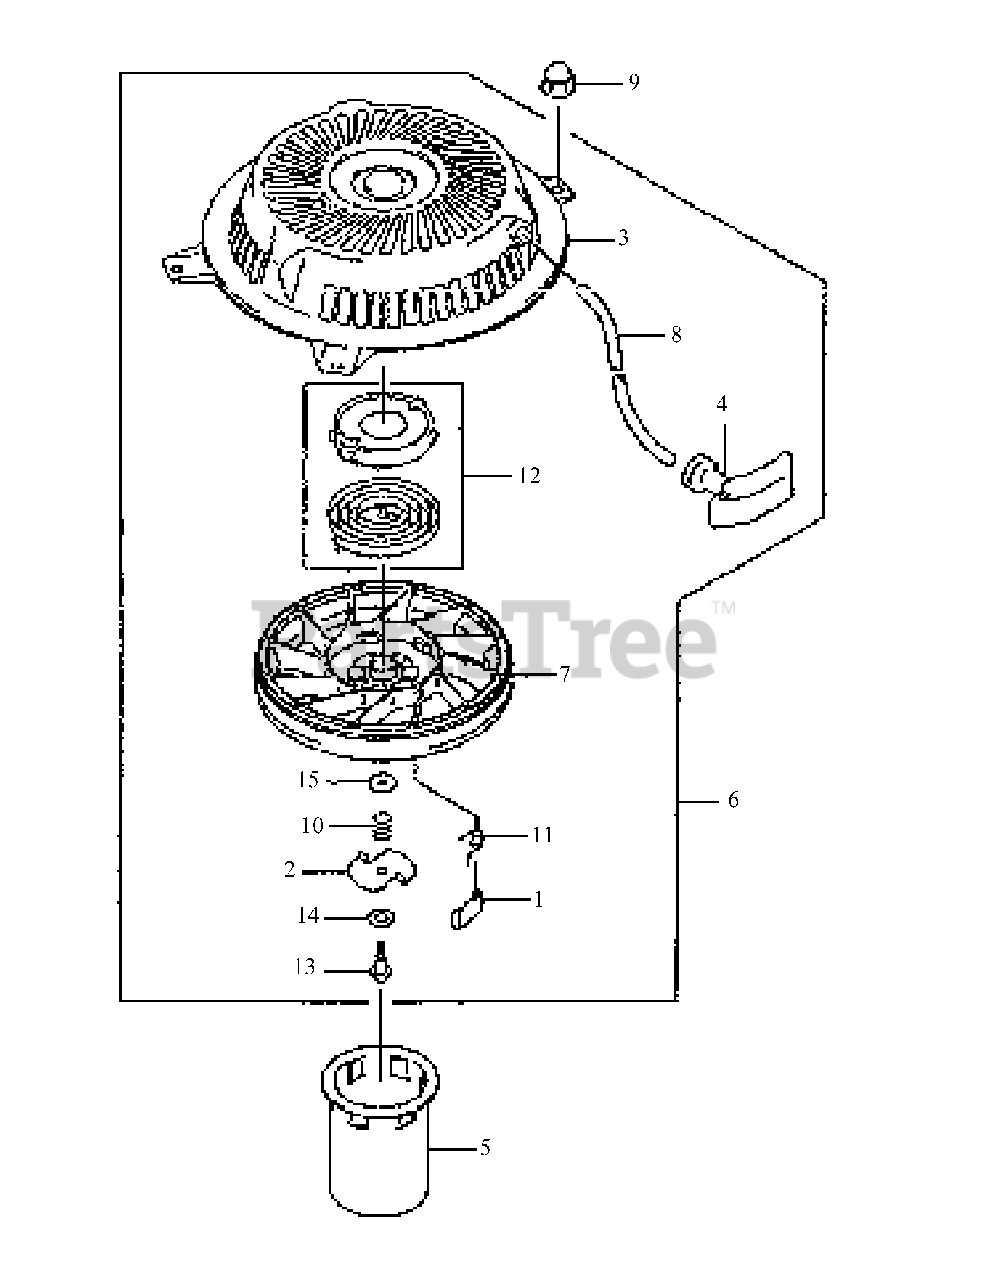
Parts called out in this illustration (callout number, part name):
1	Pawl, Recoil Starter
3	Case, Recoil Starter
4	Grip, Recoil Starter
5	Pulley, Starter
6	Starter, Recoil
7	Reel, Recoil Starter
8	Rope, Starter
